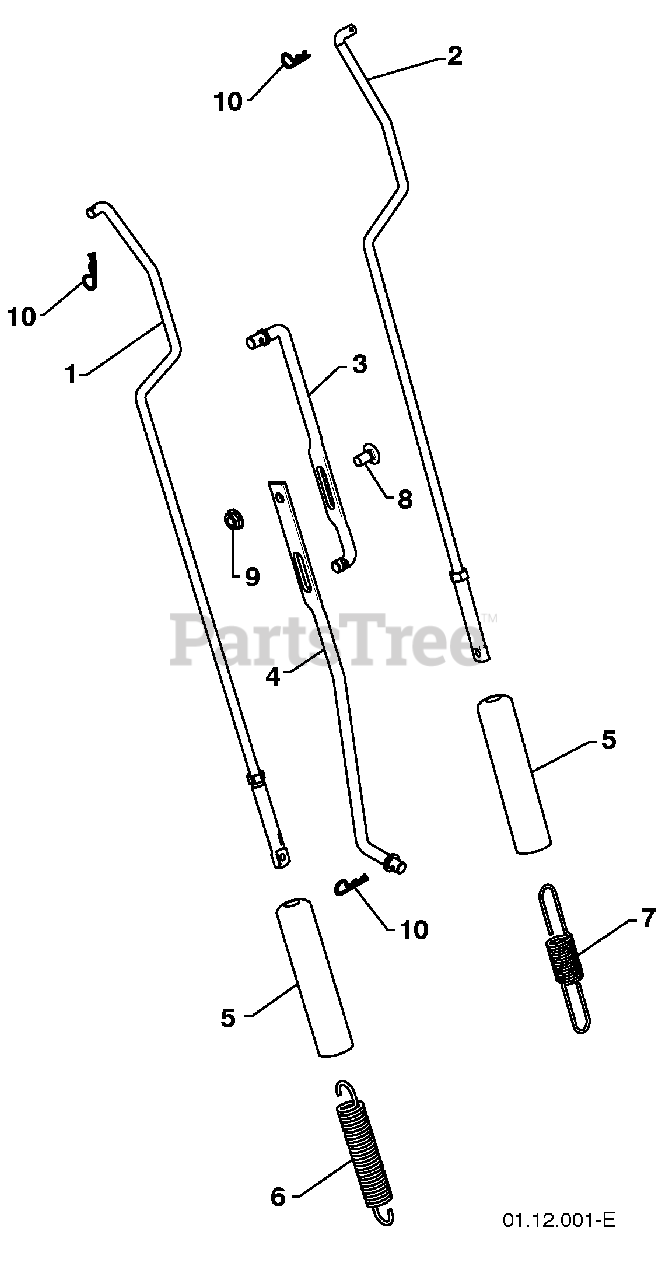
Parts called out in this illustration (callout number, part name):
1	IMPELLER ROD ASSEMBLY
2	TRACTION ROD ASSEMBLY
3	SHIFTER ROD TOP
4	SHIFTER ROD BOTTOM
5	SPRING SLEEVE
6	IMPELLER SPRING
7	TRACTION SPRING
8	CARRIAGE BOLT 5/16-18 X .75
9	NUT 5/16-18
10	RETAINER
